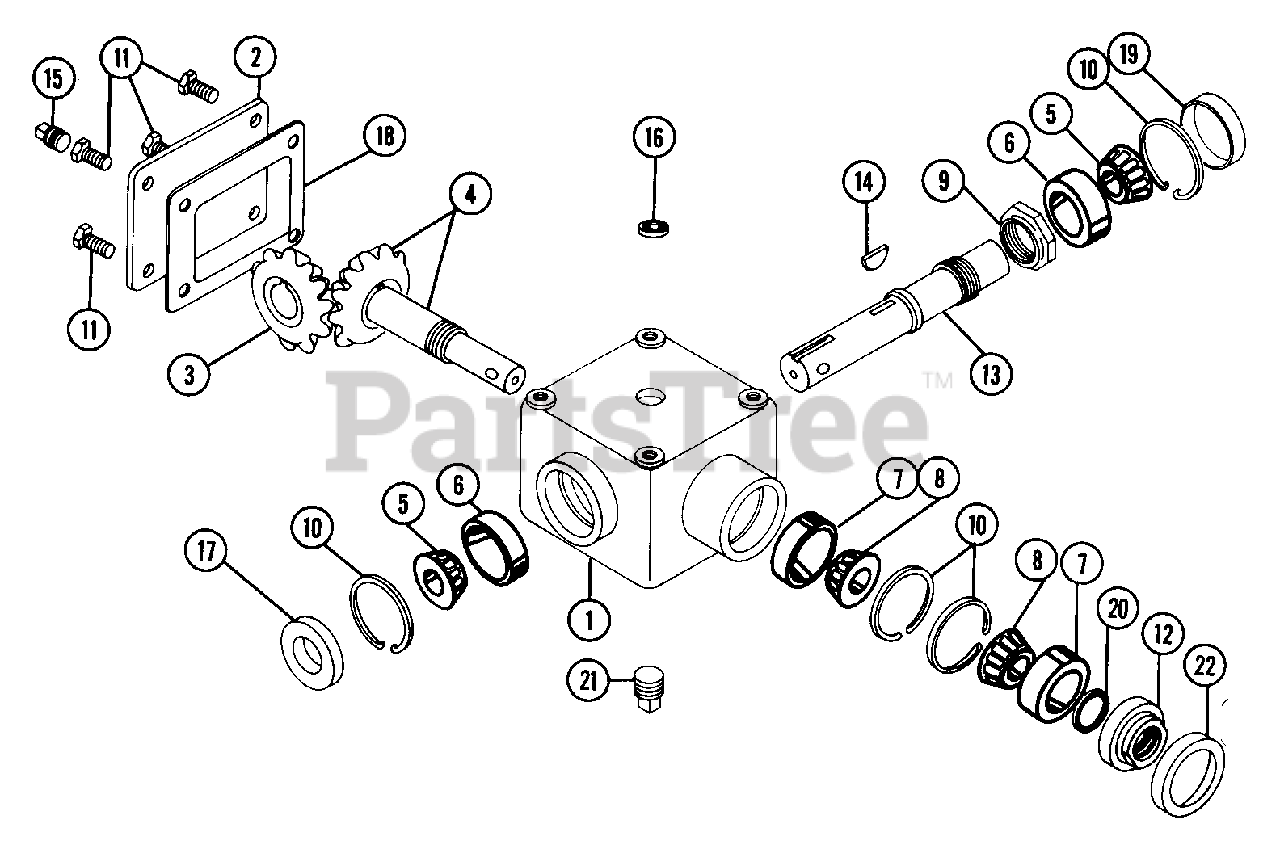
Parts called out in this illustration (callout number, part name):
1	HOUSING
3	BEVEL GEAR
4	BEVEL PINION SHAFT
5	BRG-CONE 1.0X.58
6	BRG-CUP1.980X.420
7	BRG-CUP 1.980X.420
8	BRG-CONE 29MMX.58
9	STAKE NUT
10	RG-RTNG-INT 2.000X.062
11	BLT-HEX .31-18X.63 PL GR 2
12	STAKE NUT
13	OUTPUT SHAFT
14	KEY-WDRF .25X.875X.375 SAE A
15	PLUG-LEVER
16	PLUG-DRAIN
19	SEAL 1.000X1.980X.250
20	O-RING 1.125X1.312X.093
21	VENT PLUG
22	SEAL 1.987 X1.500 X.313
